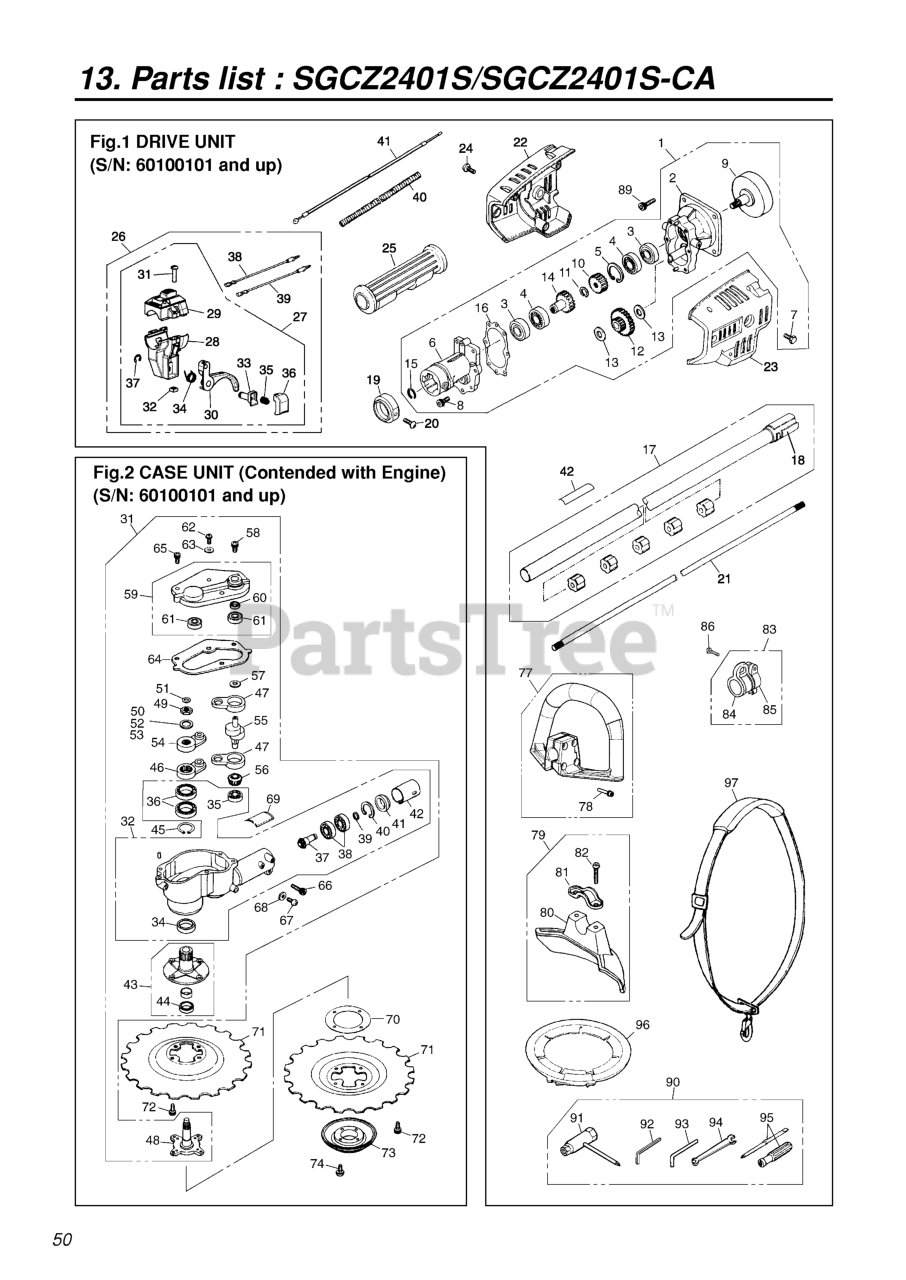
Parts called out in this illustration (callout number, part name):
1	MISSION ASSEMBLY
2	CASE, REAR COMP (RPLS -11101)
4	BEARING
5	RING, SNAP, M28 x 1.2
6	CASE, FRONT
7	BOLT, M6 x 8
8	BOLT, M5 X 20
9	DRUM
10	GEAR, PINION
11	RING, SNAP
12	GEAR (RPLS 3805-11330)
13	WASHER
14	GEAR, WHEEL
15	RING
16	GASKET (RPLS 3805-11411)
17	PIPE COMP (RPLS 3805-12100)
18	CUSHION
19	CAP
20	SCREW, M5 X 10
21	SHAFT
22	COVER, RIGHT (RPLS. -11510)
23	COVER, LEFT (RPLS -11520)
25	GRIP
26	LEVER ASSY
27	LEVER
29	COVER COMP. (RP. 6110-14410-02)
30	FLEX, TRIGGER
38	CORD (A), BLACK
39	CORD (B), RED
40	TUBE (RPLS 4900-72141)
41	CABLE COMP
42	PLATE, NAME
77	HANDLE ASSY. (REPLACES -14001)
78	SCREW
79	GUARD ASSY (RPLS -24000)
80	GUARD (RPLS -24110)
81	CLAMP (REPLACES 5807-24120)
82	BOLT, M6 x 1.30
83	HANGER COMP.
86	SCREW
89	BOLT, M6 x 20
92	WRENCH (TOOL)
93	WRENCH (TOOL)
94	SPANNER, 8 X 10 (RPLS 2540- )
95	SCREWDRIVER
96	COVER (REPLACES D0041) ACC.
97	STRAP ASSY. (USE 848-JC0-3610)
A31	CUTTERCASE ASSEMBLY
A32	CUTTERCASE (RPLS -98100)
A34	SEAL, OIL
A36	BEARING
A37	PINION
A38	BEARING (RPLS T3403-13510)
A39	RING, SNAP
A40	RING, SNAP, M26 X 1.2
A41	PACKING
A42	SPACER (RPLS -13950)
A43	SHAFT, OUTER-C
A44	SEAL, OIL
A45	RING, SNAP, M20 x 1.2
A46	ARM, LOWER (RPLS -13411)
A47	CONROD (RPLS 3805-13432)
A48	SHAFT, INNER
A50	SHIM, 0.3t
A52	SHIM, 0.2T
A53	SHIM, 0.1t
A54	ARM, UPPER (RPLS -13611)
A55	CRANKSHAFT (RPLS -13710)
A56	GEAR
A57	WASHER, M8 x 1.2
A58	BOLT
A59	COVER COMP
A60	SEAL, OIL
A62	SCREW, M6 x 10
A63	WASHER, M6 x .8
A64	GASKET
A65	BOLT, M5 x 20
A66	BOLT, M6 x 1.35
A67	SCREW, M5 x 14
A68	WASHER, M5x.8(RPLS 01624-20508
A69	LABEL, CAUTION
A71	BLADE
A72	BOLT, M6 x 8
A73	STABILIZER (RPLS -15151)
A74	SCREW, M5 X 8
